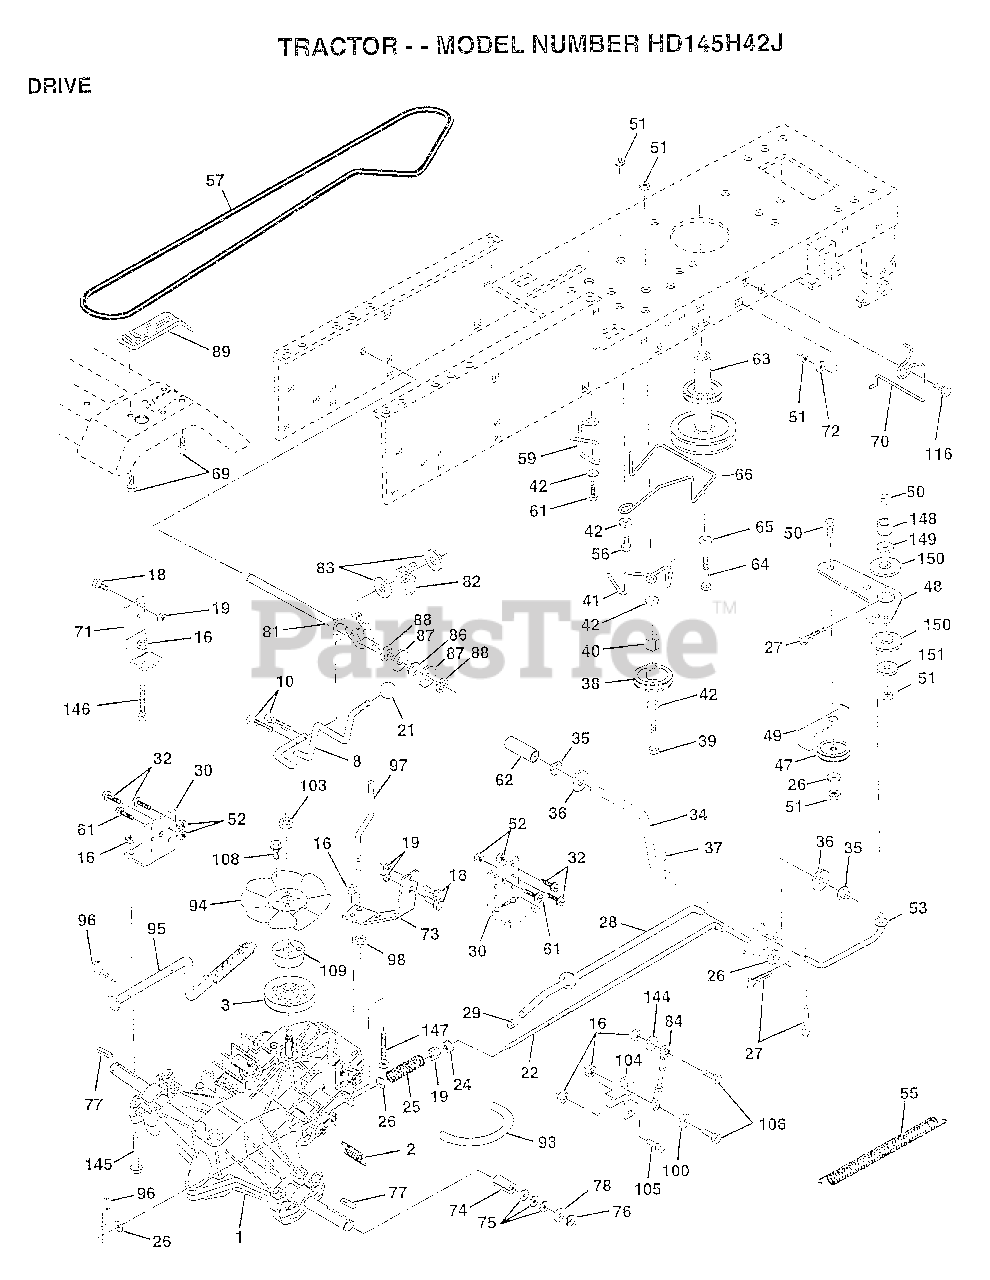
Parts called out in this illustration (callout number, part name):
1	TRANSAXLE HYD 0319-0500
2	SPRING RET BRAKE
3	PULLEY.4.20.HYDRO
8	ROD SHIFT FEND LT
10	PIN COTTER 1/8
16	NUT
18	BOLT
19	NUT
21	KNOB T (1/2-HOLE)
22	ROD.BRAKE.HYDRO.
24	NUT
25	SPRING ROD LT
26	WASHER
27	COTTER PIN
28	ROD.BRAKE.PARK.LT
29	PLUNGER CAP T
30	TRANSAXLE MTG BKT
32	BOLT
34	SHAFT ASM-PEDAL F
35	NYLON BEARING
36	WASHER LT
38	PULLEY.IDLER.FLAT
39	BOLT
40	SPACER T
42	WASHER
48	BELLCRANK.CLUTCH
49	RETAIN BELT
53	"LINK, CLUTCH T"
55	"SPRING, RETURN LT"
57	BELT-V.HYDR.84.61
59	KEEPER BELT CNTSP
61	SCREW
62	PEDAL COVER T
63	PULLEY.ENGINE
64	BOLT
65	LOCKWASHER
66	KEEPER-BELT
69	SCREW HEXWSH H-L
70	KEEPER BELT ENG
71	STRAP.TORQ.LH.HYD
72	WASHER
73	STRAP.TORQ.RH.HYD
74	SPACER SPLIT
76	E-RING LT
77	SQUARE KEY
78	WASHER
81	SHAFT.CROS.500.HY
82	"SPRING,TORSION"
83	WASHER
84	ROD.TIE.BALL.HYD.
86	BUSHING
87	WASHER D
88	KLIP RING
93	"LINE FUEL HYD 4"""
94	"FAN 7"" HYDRO"
97	KEEPER.BELT.RH.HY
98	NUT
100	WASHER M
104	ARM.CONTROL.PUMP
105	SCREW CAP 5/16-18
106	BOLT
108	SCREW.HXHD.10-20
109	ADAPTOR.FAN.HYDRO
116	BOLT RDHD 3/8-16
144	WASHER
145	BOLT.HEX.FLGHD
146	BOLT.HEX.FLGHD.
147	BOLT.HEX.FLGHD
149	SPACER RETAINER
150	BUSHING.NYLON
151	WASHER
